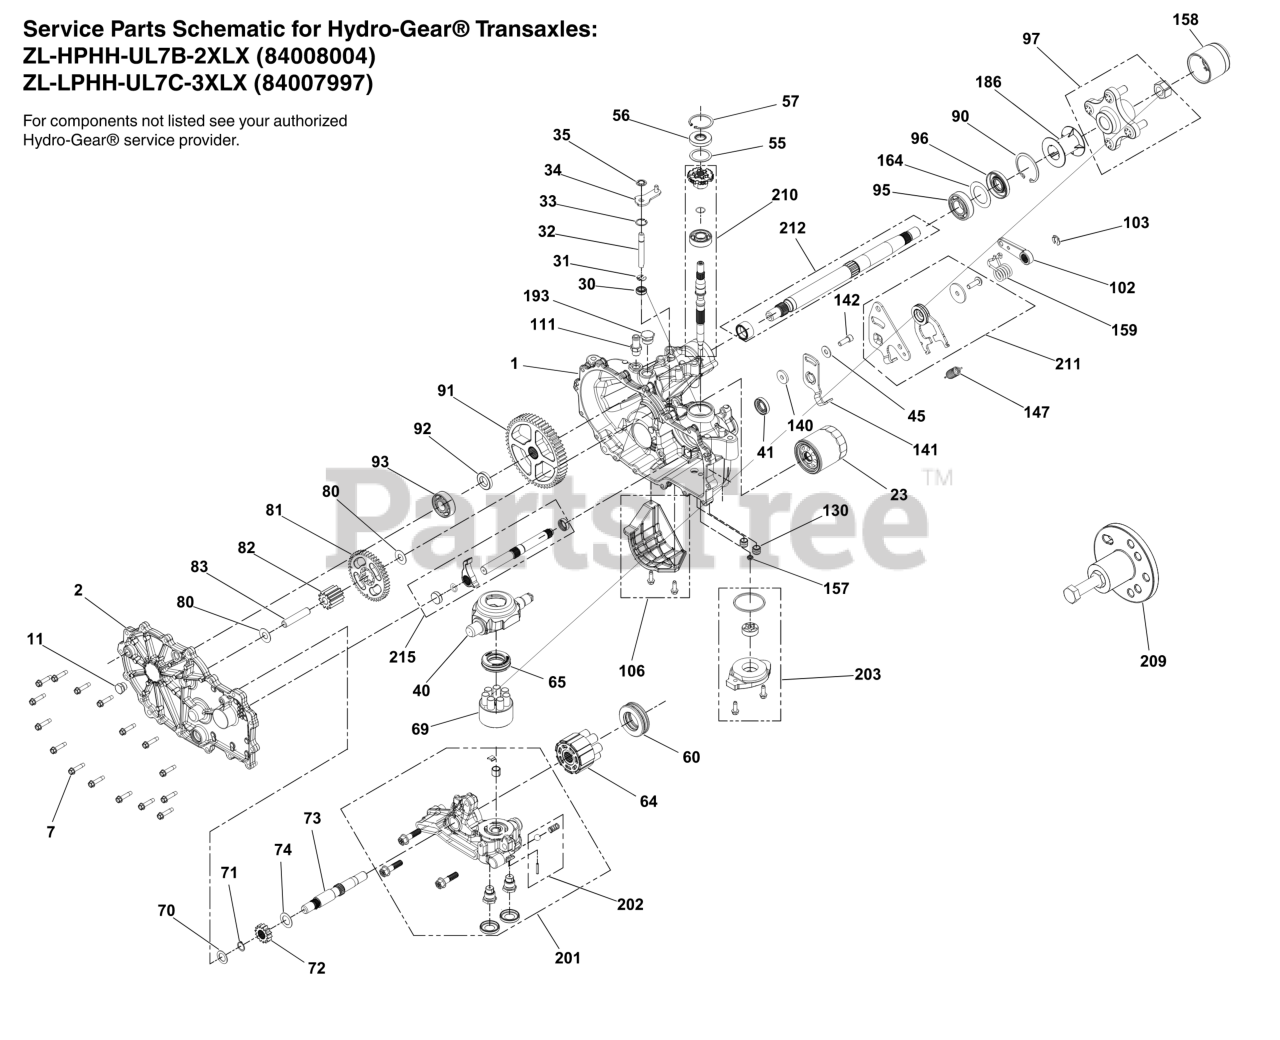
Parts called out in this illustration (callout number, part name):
1	KIT, HOUSING, MAIN, LH, CHRG, CNTL
2	KIT, SIDE COVER, LH
7	SCREW, HEX WASHER
13	TUBE, SEALANT
23	FILTER, OIL, ZT2800
30	SEAL, Lip
34	ARM, BYPASS
35	RING, RETAINING .375 EXTERNAL
40	SWASHPLATE, TRUNNION
41	SEAL, LIP
56	SEAL, LIP 17 40 7 HNBR
57	RING, RET 2.06 INT,
64	KIT, 16cc CYLINDER BLOCK ASSEMBLY STEAM TREAT
69	KIT, BLOCK 7 PISTON
70	WASHER, .63 X 1.00 X .05 FLAT
71	RING-SNAP (44145)
72	GEAR, 14T (STEEL)
73	SHAFT, MOTOR
74	WASHER, .71 X 1.16 X .04 FLAT
80	WASHER, .51 X 1.00 X .03 FLAT
82	GEAR, 11T (STEEL)
83	PIN, JACKSHAFT
90	RING, RETAINING 2.25 INTERNAL (50859)
93	KIT, BEARING, ZT-3400, 72749
95	BEARING, BALL, 1.0 X 52 X 15 OPEN 6205M
96	KIT, SEAL, AXLE - HG# 53699
97	HUB, ASM, TRANS 5101188/89 & 5102154/55
102	BRAKE ARM, ZT-3400
106	KIT, FILTER GUARD
111	KIT, FITTING 1/2 BEADED 9/16 SAE
130	TUBE, CHARGE TRIPLE O-RING
141	ARM, NEUTRAL, LH
142	SHCS, 5/16-24 X .875 (PATCH)
147	SPRING, Extension
157	KIT, GEROTOR SEAL
158	CAP, AXLE, ZT-3400, 53501
159	SPRING, TORSION, CW
164	WASHER, 1.355 x 2.035 x .021 FLAT
186	DEBRIS GUARD HG #53496
201	KIT, CENTER SECTION, LH CHARGE
202	KIT, CHARGE RELIEF
203	KIT, CHARGE
209	KIT, HUB PULLER
210	KIT, INPUT SHAFT
211	ARM, Control Kit L.H.
212	KIT, SHAFT, AXLE
215	KIT, OUTBOARD, RH ROT B / LH ROT A
